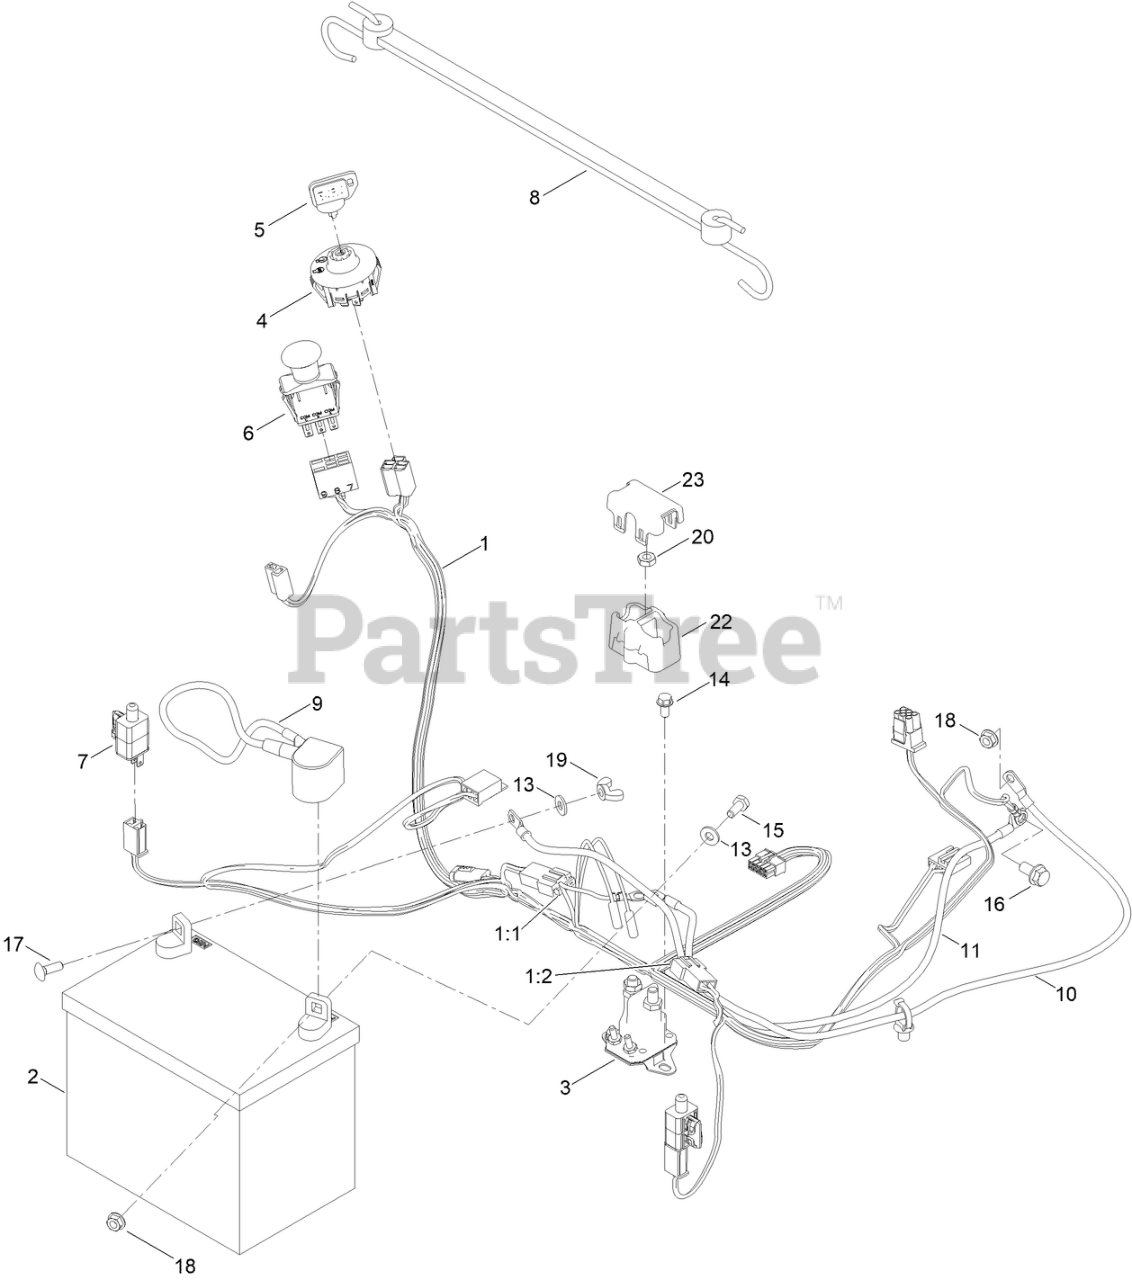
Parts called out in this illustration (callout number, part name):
1	HARNESS-WIRE
1:1	FUSE-BLADE, 15 AMP
1:2	FUSE-BLADE, 25 AMP
2	BATTERY
3	SOLENOID
4	SWITCH-IGNITION
5	KEY-IGNITION
6	SWITCH-PTO
7	SWITCH
8	STRAP-RUBBER
9	CABLE-BATTERY, POS
10	CABLE-BATTERY, RED (8 GAUGE)
11	CABLE-BATTERY, BLACK
13	WASHER-FLAT
14	SCREW-HWH
15	SCREW-HH
16	SCREW-HHF
17	BOLT-CARR
18	NUT-HF
19	NUT-WING
20	NUT-HJ
22	COVER-SOLENOID
23	CAP-SOLENOID
